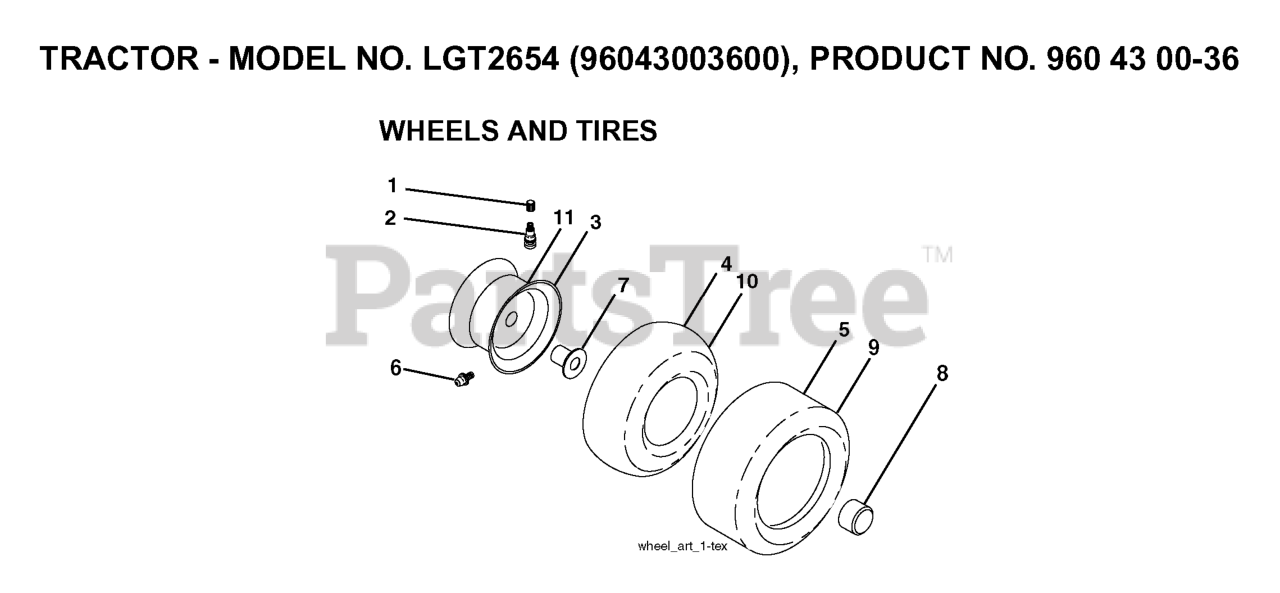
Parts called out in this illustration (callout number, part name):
2	VALVE STEM LT
3	RIM ASSEMBLY, FRONT
4	TUBE.5.3/4.5/6
5	TIRE HEAVY DUTY
6	FITTING LT
7	BEARING T
8	CAP, AXLE BLK
9	TIRE.22X9.50-12.TURF.SAVER.REA
10	TIRE.22X9.50-12.TURF.SAVER.REA
11	RIM.ASM.12".REAR.SILVER
